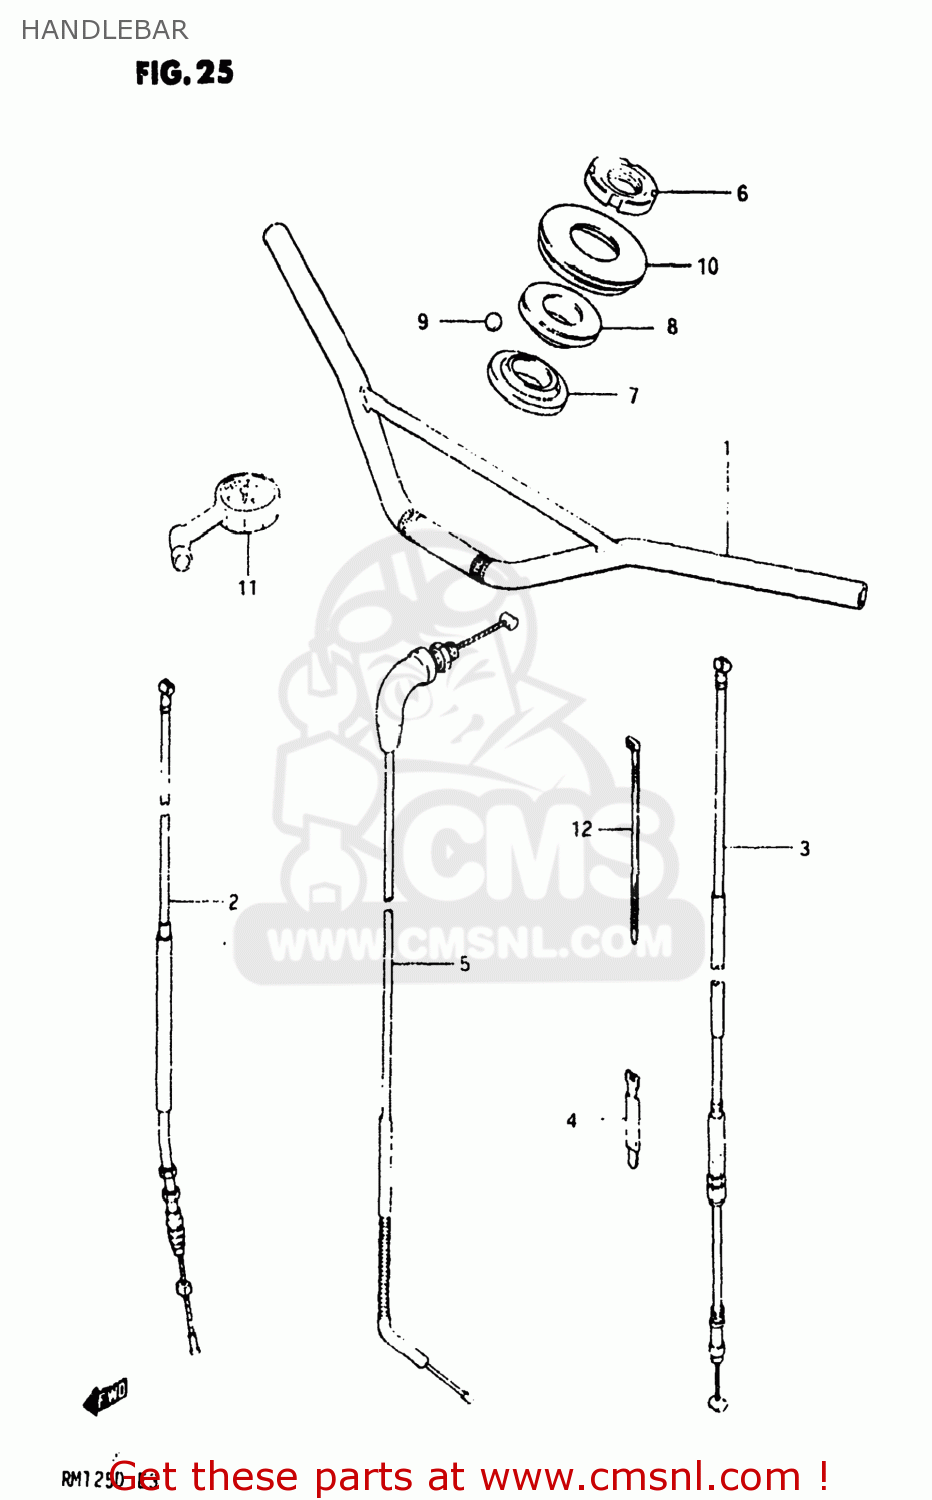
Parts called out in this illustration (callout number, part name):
1	HANDLEBAR
2	CABLE ASSY,FR BRAKE
3	CABLE ASSY,CLUTCH
4	CLAMP
5	CABLE ASSEMBLY,THROTTLE
6	NUT,STEERING STEM
7	RACE,STEERING,INNER,UPPER
8	RACE,STEERING,OUTER,UPPER
9	BALL
10	SEAL,STEERING UPR DUST
11	GAUGE ASSY,AIR PRESSURE
12	CLAMP
